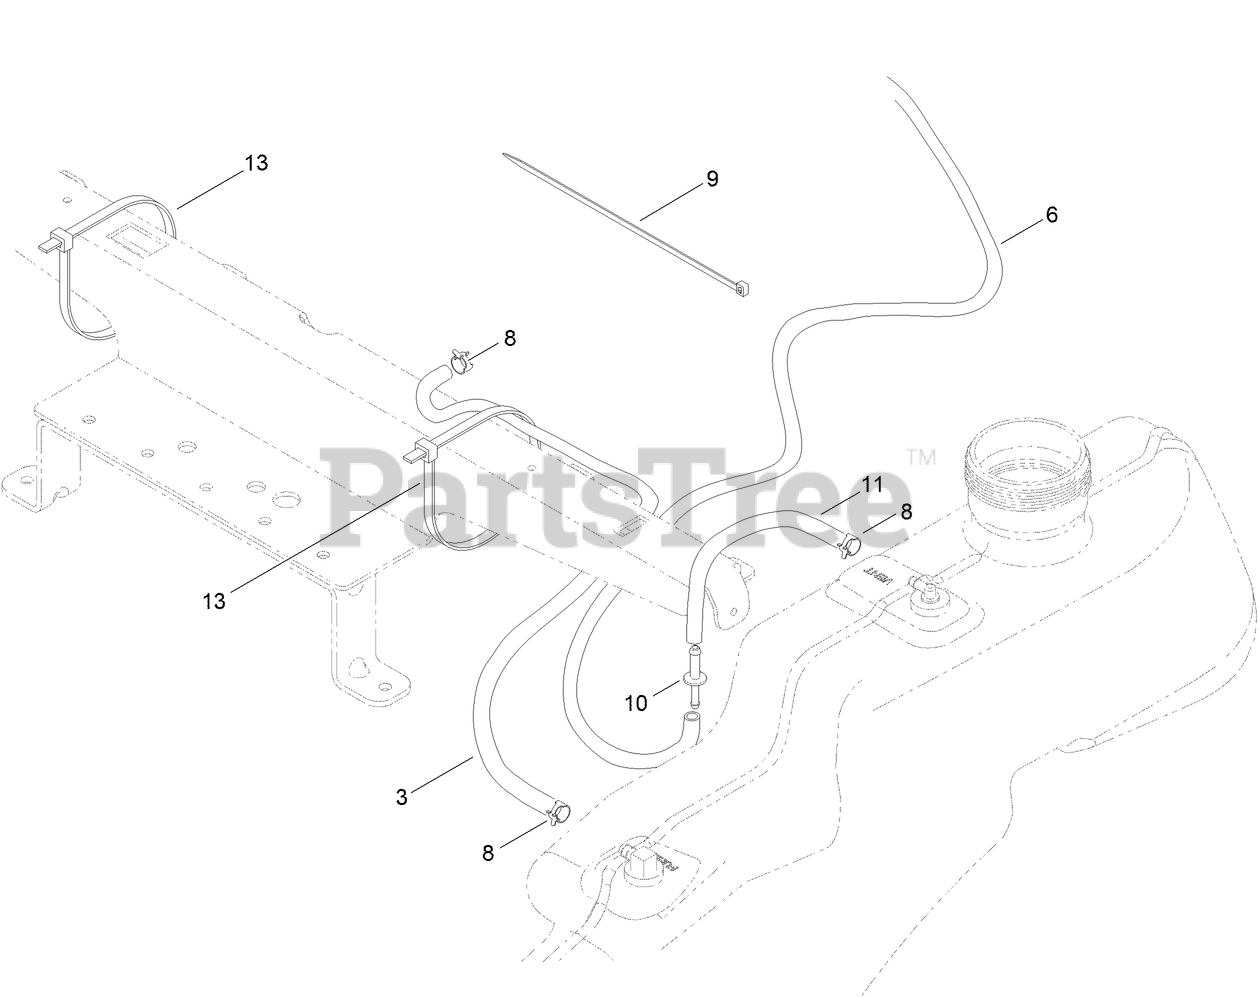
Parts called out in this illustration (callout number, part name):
3	HOSE-FUEL
6	Hose-Fuel
8	CLAMP-HOSE
9	TIE-CABLE
10	ADAPTOR-ORIFICE
11	HOSE-FUEL
13	TIE-CABLE
